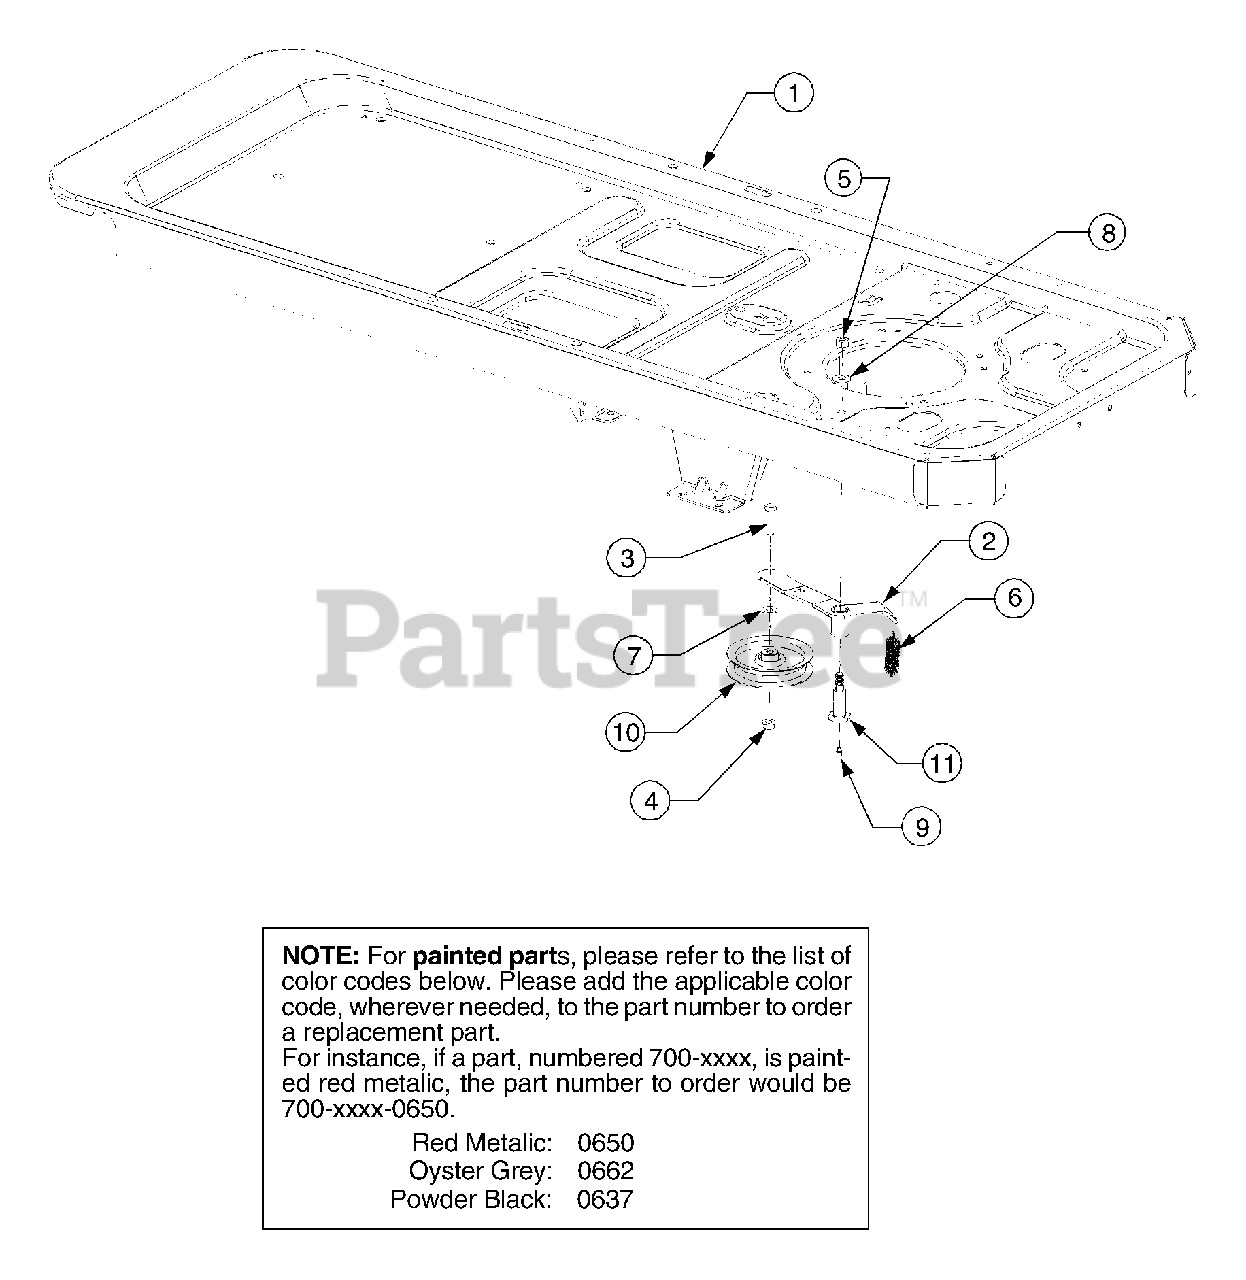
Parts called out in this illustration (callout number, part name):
4	Nut, Hex Flange Lock, 3/-16 GRF
5	Nut, Hex Lock, 7/16-14 GRA
6	Spring, Extension, .75 x 5.06
7	Washer, Flat, .406 x .875 x .059
8	Washer, Flat, .45 x 1.25 x .164 HT
9	Fitting, Lube, 3/16 Drive
10	Screw, Shoulder, .68 x 1.59
11	Pulley, Idler, 4.08 Dia.
